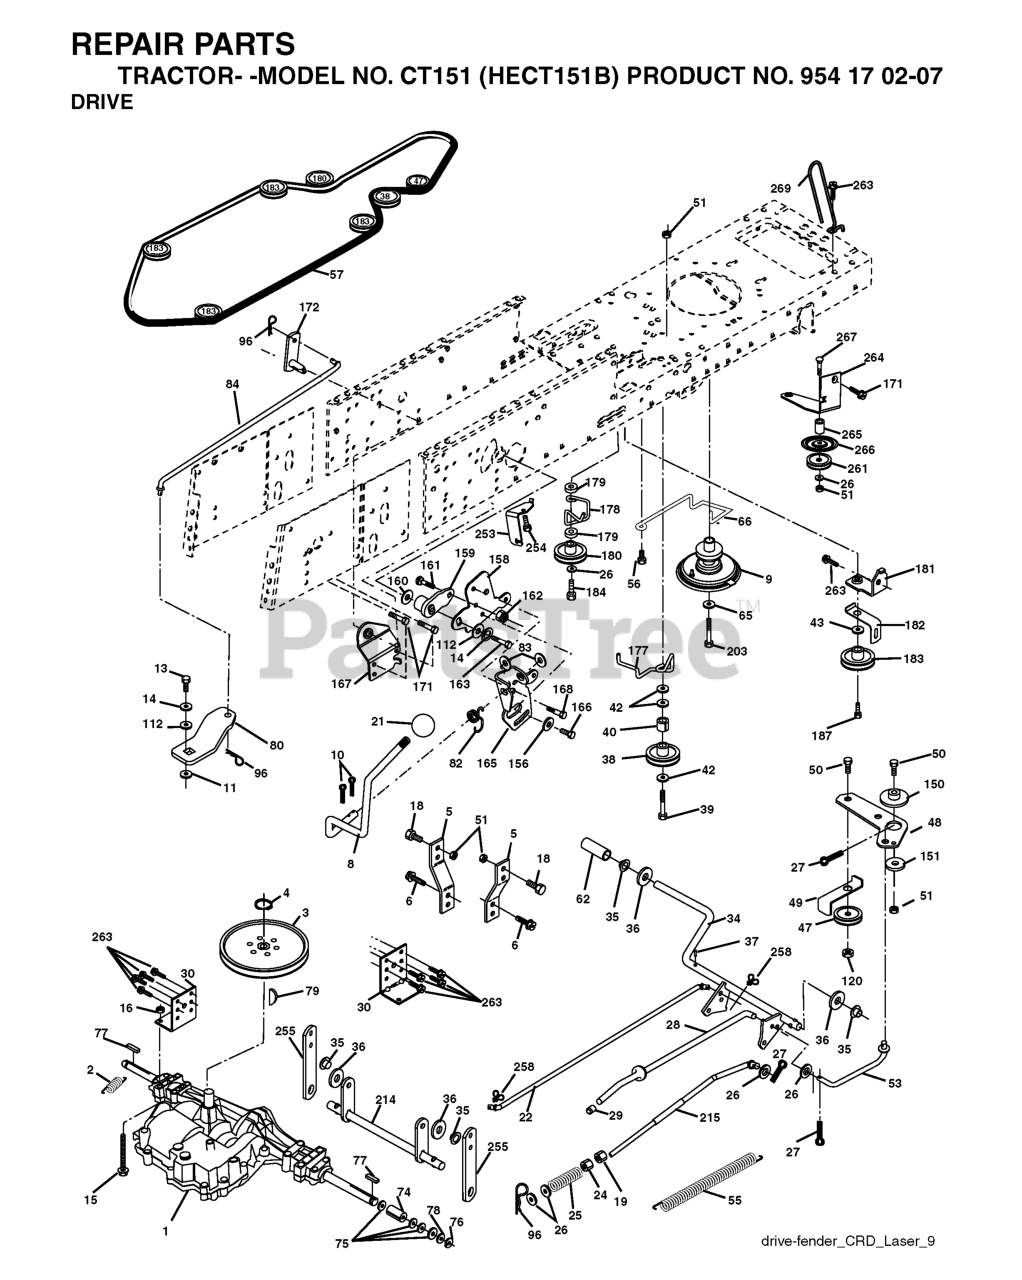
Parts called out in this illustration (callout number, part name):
2	SPRING,BRAKE RETURN
3	PULLEY
4	RETAINING RING LT
5	STRAP TORQUE
6	SCREW 5/16"
8	ROD.SHIFT.FENDER.ADJ.LT.CRD
9	RP CLUTCH.NORAM.2002
10	PIN COTTER
11	WASH-SHFT PLT LT
13	BOLT 1/4-28X3/4
14	LOCKWASHER
15	BOLT HEX 5/16-18 GR 5
16	NUT.71038.31-18.HEX.NYLOCK
19	NUT
21	KNOB.DUCKHEAD.1/2
22	ROD
24	NUT
25	SPRING ROD LT
26	WASHER
27	COTTER PIN
28	ROD, PARKING BRAKE
29	PLUNGER CAP
30	BRKT, MOUNT TRNSAXLE
34	SHAFT, FOOT PEDAL
35	BEARING.NYLON
37	DRIVE PIN
38	PULLEY.FLAT
42	WASHER
47	IDLER PULLEY
48	BELLCRANK, CLUTCH
49	RETAIN BELT
50	BOLT.3/8-16X1.50
53	LINK, CLUTCH LT
55	SPRING, RETURN LT
56	SCREW.3/8-16
57	V-BELT.KEV.111"
62	COVER, PEDAL (1 2)
65	LOCKWASHER
66	KEEPER BELT ENGINE
74	SPACER AXLE
77	SQUARE KEY
79	KEY STD (1373) DANA
82	SHIFT SPRING
83	WASHER
96	RETAINER M
120	NUT LOCK FLG 3/8-16 UNC
150	BUSHING.BELLCRANK.GRD.DR
151	WASHER 12/32X2X10GA
156	WASHER.SRRTD.5/16
158	BRACKET
159	RB HUB.SHIFT
161	BOLT
162	NUT.CROWNLOCK.1/4
165	RP BRACKET
166	CAPSCREW.HXHD.FLG.5/16-18X.625
167	BRACKET.SUPT.SHIFT.CRD
168	BOLT.SHOULDER.5/16-18X
172	SHAFT
180	PULLEY.FLAT.IDLER
181	BRACKET
182	BELT GUIDE
184	SCREW.HXWSH.3/8
187	BOLT.5/16-18X1.25
203	BOLT.HEX.7/16-20 X 5
207	WASHER NYL
214	LEVER
254	SCREW 3/8-16X1
255	SHAFT
258	CLIP RETAINER
261	FLAT IDLER PULLEY
263	SCREW, 3/8-16X3/4
265	SPACER IDLER
266	PROTECTOR
268	GUARD MUFFLER
275	WASHER
